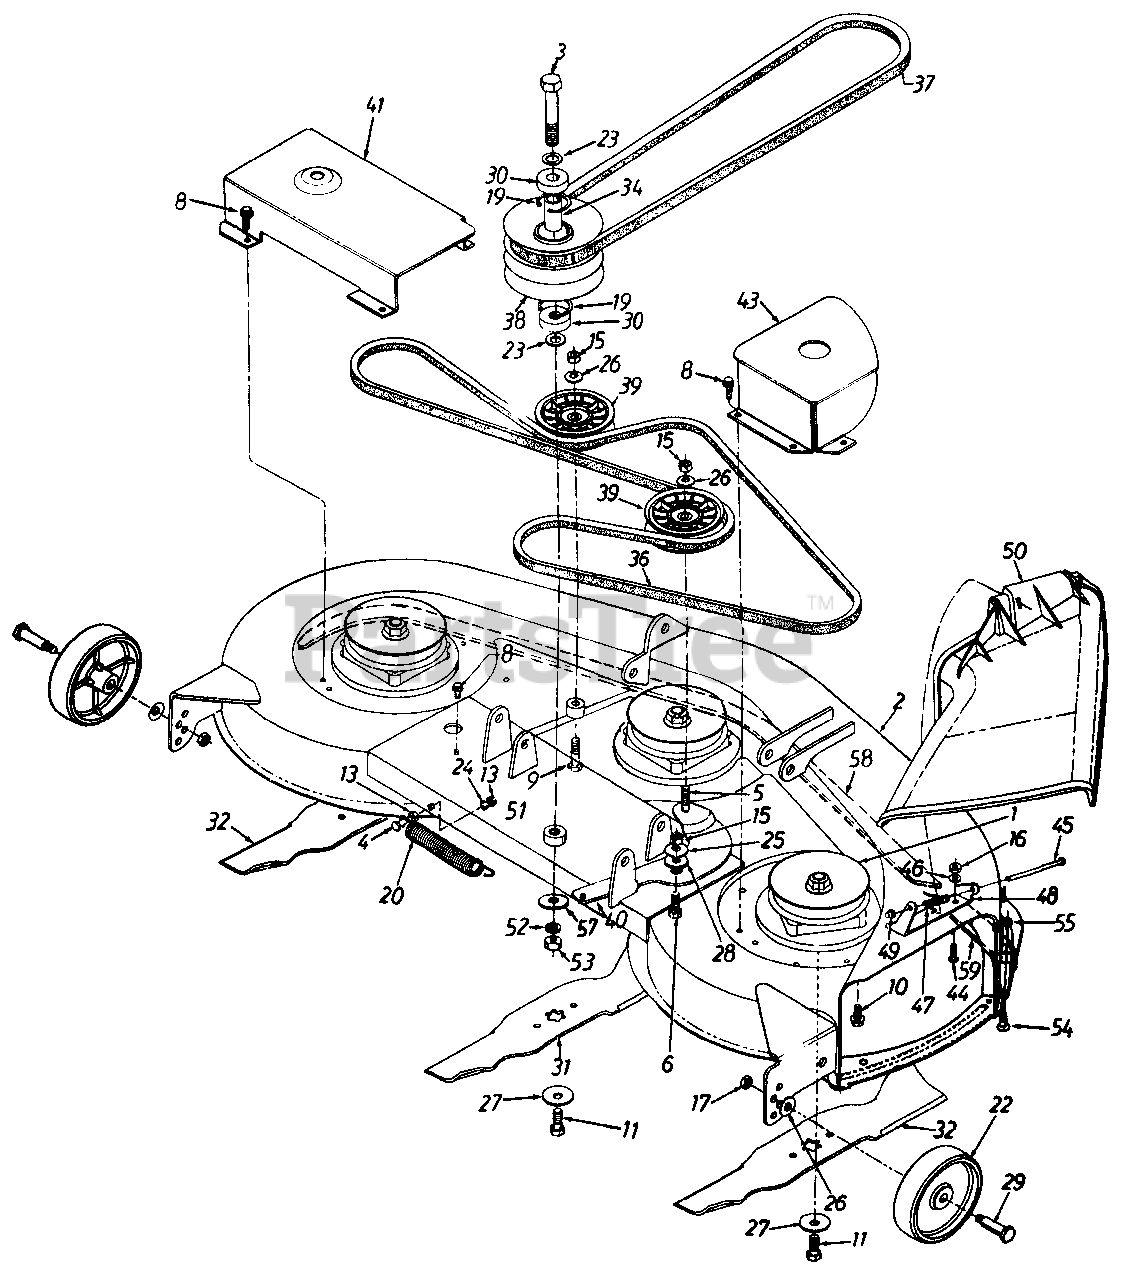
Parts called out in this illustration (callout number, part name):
1	Blade Spindle Ass'y.
2	46" Deck Ass'y.
4	Hex Bolt 1/4-28 x 1.25" Lg.
5	Hex Bolt 3/8-24 x 1.5" Lg.
6	Hex Bolt 3/8-24 x 1" Lg.
8	Hex Wash. Hd, TT-Tap Scr. 1/4-20 x .5" Lg.
9	Hex Bolt 3/8-24 x 2" Lg.
10	Hex Flange Bolt 5/16-24 x .75" Lg.
11	Hex Patch L-Bolt 7/16-20 x 1" Lg,
13	Hex Nut 1/4-28 Thd.
15	Hex Nut 3/8-24 Thd.
16	Hex Nut 1/4-20 Thd.
17	Hex Top Jam Nut 3/8-16 Thd.
19	Int. Snap Ring
20	Ext. Spring .88" O.D. x 6.17"
22	Deck Wheel
23	Fl-Wash. .635" I.D. x 1" O.D. x .06"
24	L-Wash. 1/4" I.D.
25	Bell-Wash. 3/8" x 1.125" x .062"
26	Bell-Wash. 3/8" x .87" x .064"
28	Shoulder Spacer.625" I.D. x .169"
29	Shld. Bolt .498" x 1.525"
30	Ball Brg. .625" I.D. x 1.574" O.D. x .47"
31	High Lift Blade 14.88" Lg.
32	High Lift Blade 16.28" Lg.
34	Spacer .635" I.0. x .088" O.D.
36	V-Belt
37	V-Belt
38	Pulley Double Deck 5" O.D.
39	Flat Idler Pulley 3.5 O.D.
44	Hex Bolt 1/4-20 x .62" Lg.
45	Hinge Pin
46	Bell-Wash. 1/4" I.D.
47	Torsion Spring
48	Hinge Mtg. Brkt.
50	Chute Ass'y. Comp.
51	Spacer .635" I.D. x 1" O.D.
52	L-Wash. 5/8" I.D.
53	Hex Nut 5/8-18 Thd.
54	Carriage Bolt 1/4-20 x .5" Lg.
55	Hex Sems Nut 1/4-20 Thd.
57	Fl-Wash. .635" I.D.
